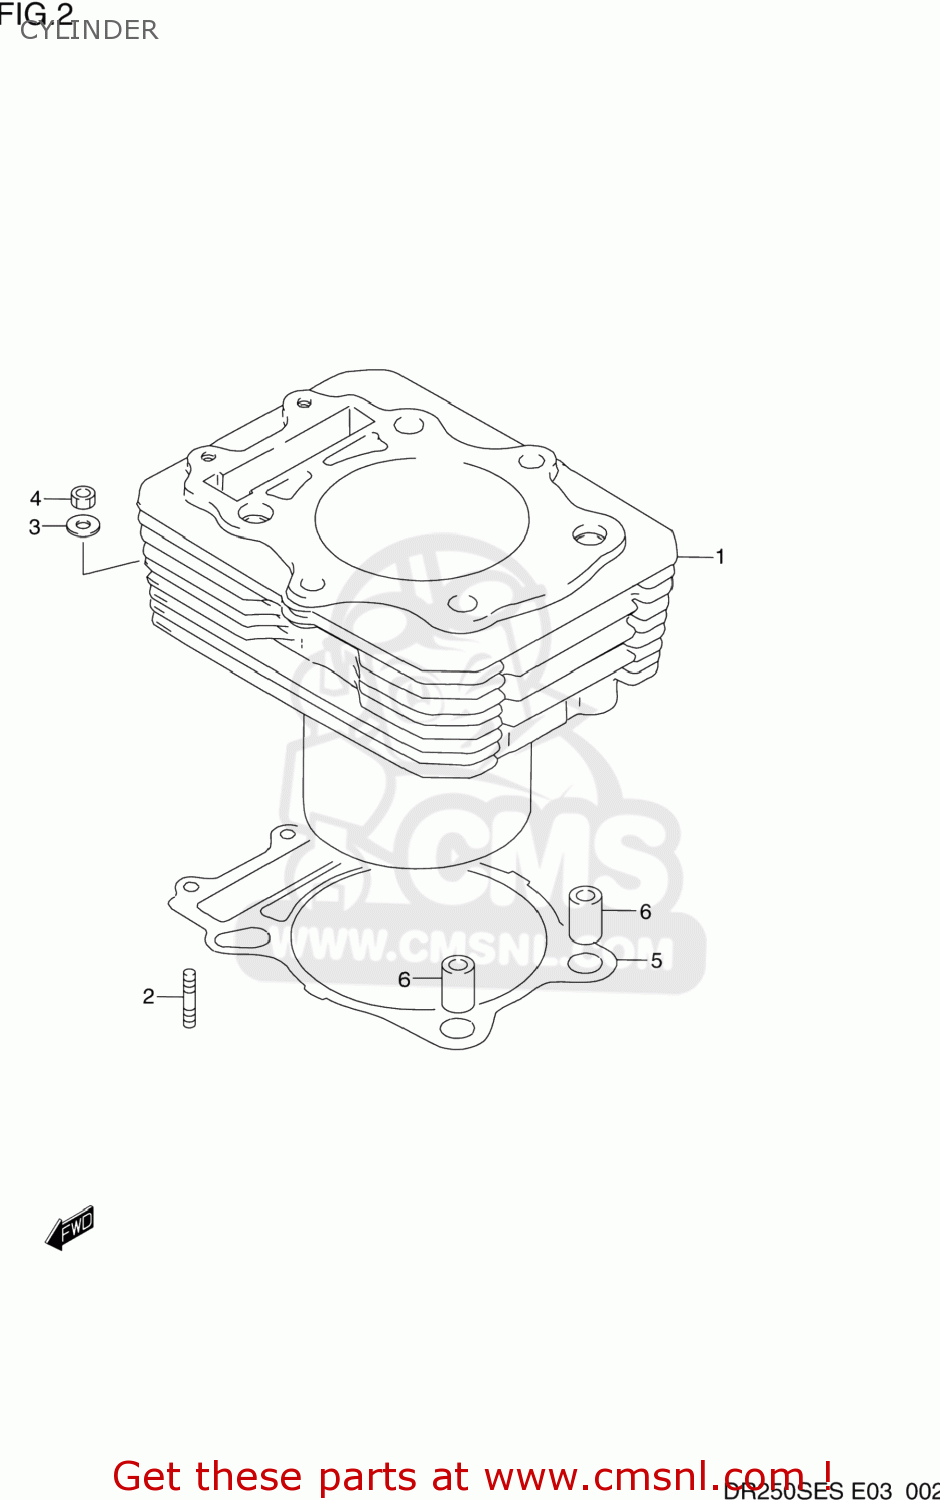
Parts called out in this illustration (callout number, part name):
1	CYLINDER
2	STUD 6X20
3	WASHER
4	NUT
5	GASKET,CYLINDER (NAS)
6	PIN
